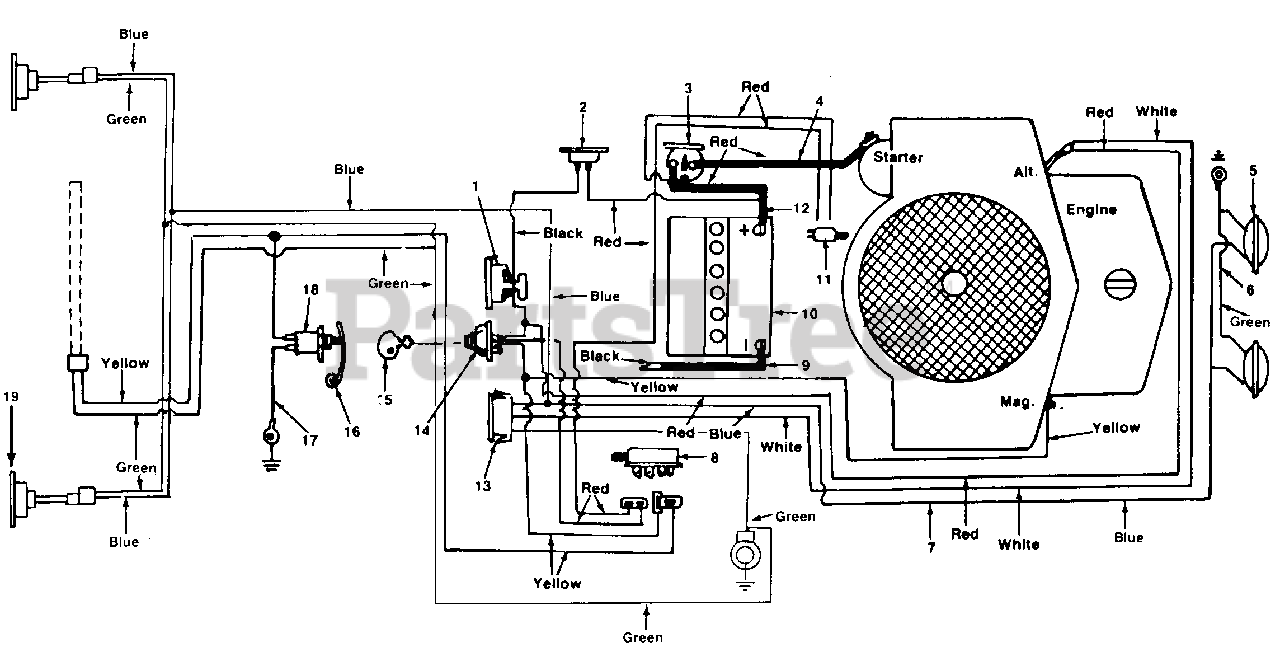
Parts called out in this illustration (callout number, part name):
1	Ammeter
2	Circuit Breaker
3	Solenoid
4	Wire
5	Headlight
6	Ground Wire
7	Wire Harness
8	Safety Switch
9	6 Ga. Black Wire
10	Battery 12V
11	Safety Switch
13	Light Switch
14	Ignition Switch
15	Ignition Key
16	Spring Lever
17	Electric Wire
18	Safety Switch
19	Taillight
